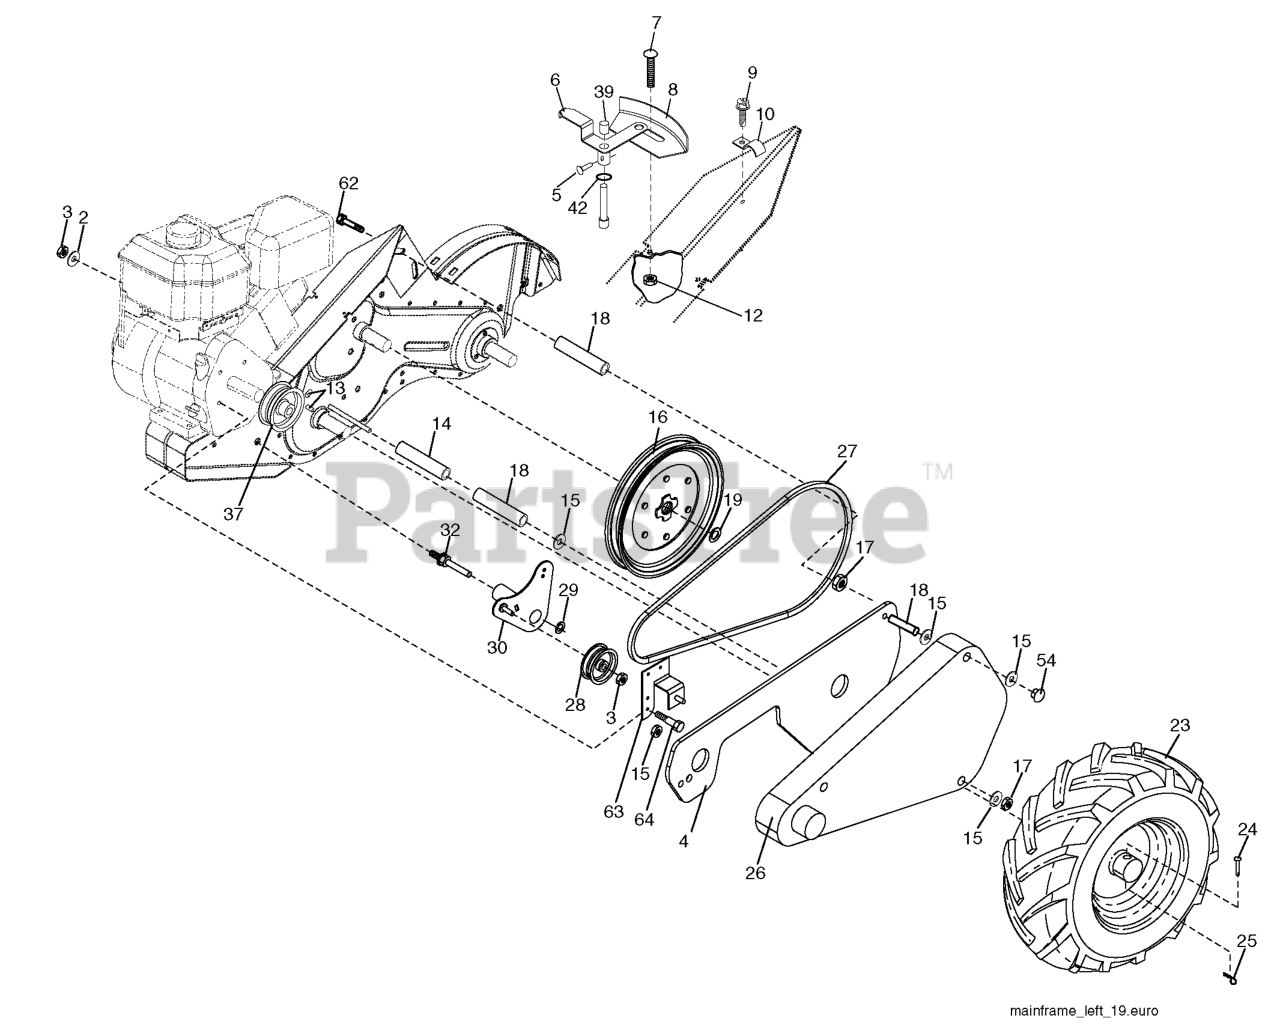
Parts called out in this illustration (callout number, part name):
2	WASHER, LOCK 3/8
3	NUT.HEX.3/8-16UNC
4	Shield, Inner Belt Guard RT
5	PIN.SPIROL.FLARED
6	LEVER ASM CRT
8	PANEL.INDICATOR.SHIFT.BLACK
9	TAPPING SCREW
10	CONDUIT.CLIP.PLATED
12	NUT
14	SPACER-SPLIT.327 X .42
15	WASHER
16	SHEAVE, TRANSMISSION
17	NUT
18	SPACER SPLIT
19	RETAINING RING LT
23	TIRE.16X4-8.CHEVRON.TILLER
25	SPRING TI
26	FOOTREST.PNT.LH
27	BELT, DRIVE
28	PULLEY-IDLER TI
30	BRACKET.ASM.IDLER.BLACK
32	SHAFT, IDLER ARM
37	SHEAVE, ENGINE
39	CAP.PLUNGER.BLACK
62	BOLT 5/16-18X4 1/2
63	Bracket Asm Guard
